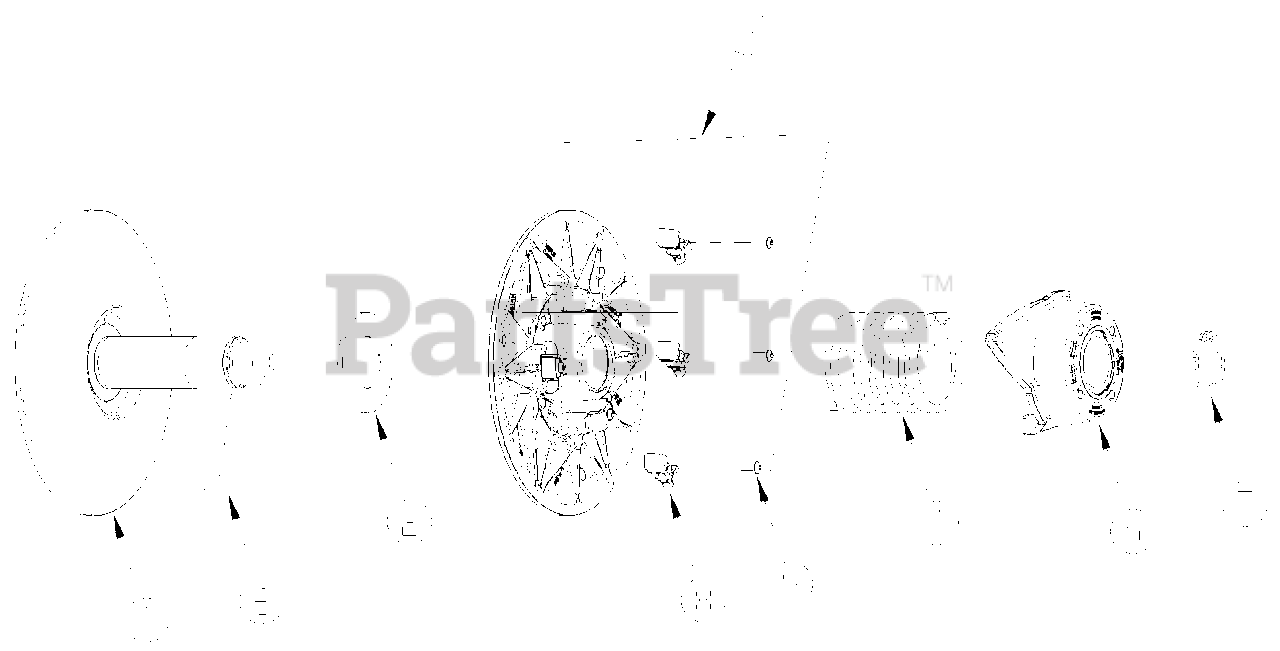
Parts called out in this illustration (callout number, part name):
1	FIXED FLANGE
2	SHIM WASHER
3	SLIDING FLANGE
4	SPRING
6	SQUARE KEY 1/4
7	SNAP RING
8	CAM SHOE
9	HEX. SCOKET BUTTON HEAD
